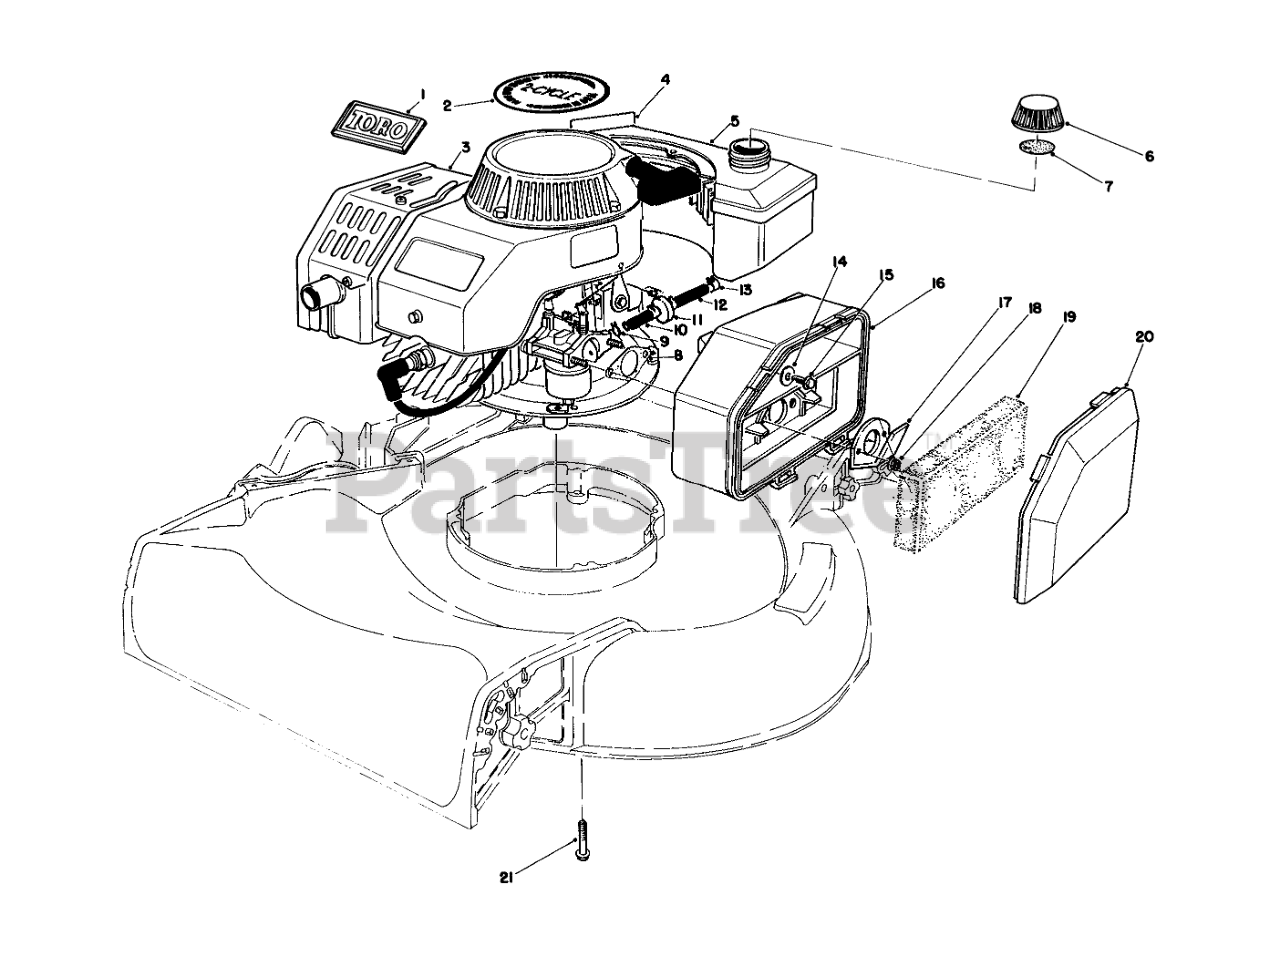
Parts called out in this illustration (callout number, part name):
1	TORO LOGO PLT
2	DECAL- 2 CYC RECOIL
3	Engine
4	Decal-Maintenance
5	Fuel Tank Assembly
6	Gas Cap Assembly (Incl. Ref. #7)
7	GAS CAP GASKET
8	GASKET-AIR CLEANER
9	CLAMP-HOSE
10	HOSE-FUEL
11	FILTER-FUEL
12	HOSE-FUEL
13	CLAMP-FUEL LINE
14	WASHER-FLAT
15	SCREW-HH
16	AIR CLEANER
17	SPIT BACK DEFLECTOR
18	NUT-LOCK
19	FILTER
20	AIR CLEANER COVER
21	FLG SCREW,3/8-16X2.000
